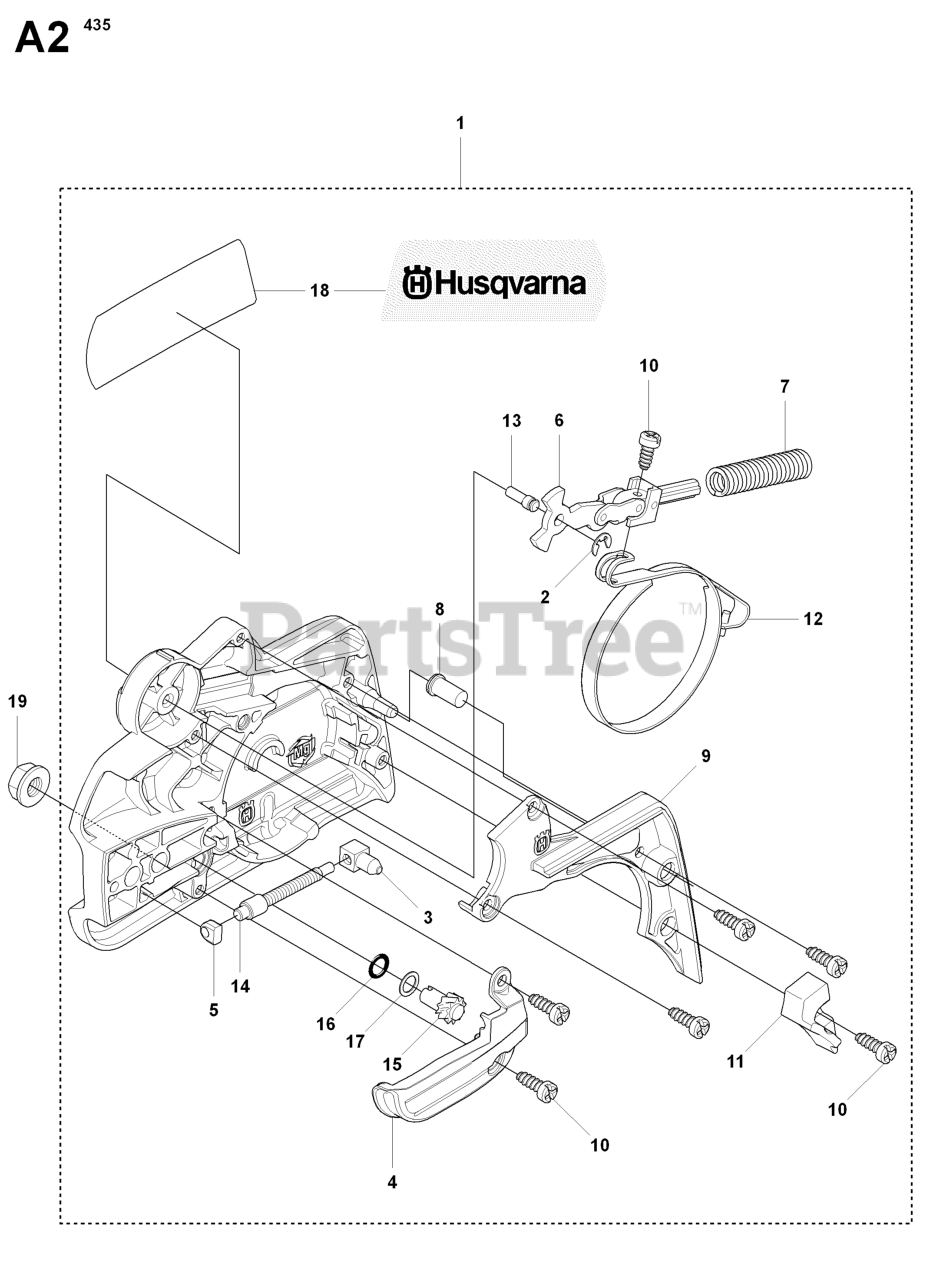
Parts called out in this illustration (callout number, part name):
1	CLUTCH COVER ASSY
4	CHAIN GUIDE
7	BRAKE SPRING
11	WEAR PROTECTION
12	BRAKE BAND ASSY
15	WORM WHEEL
18	LABEL 400 SERIES
19	NUT M8 FLANGE
